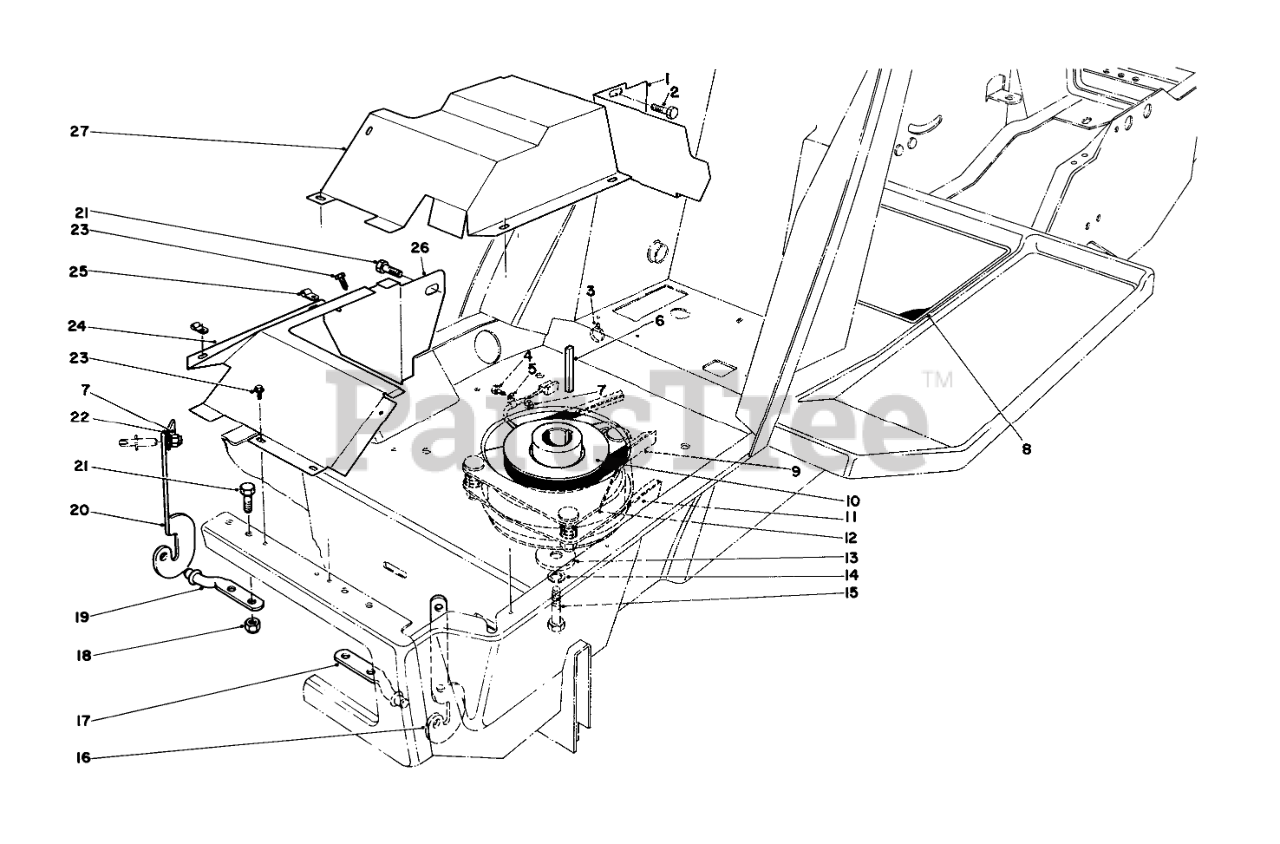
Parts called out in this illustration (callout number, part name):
1	EXH SHIELD SUPT B
2	SCREW-HH
3	TIE-MOUNT, PUSH
4	SCREW-HH
5	CLAMP
6	KEY-SQUARE
7	NUT-LOCK, NI
8	OPERATION DECAL
9	V BELT
10	Pulley
11	V BELT
12	Clutch Assembly-Deck
13	WASHER-CLUTCH
14	WASHER-LOCK
15	SCREW-HH
16	L.H. HINGE BRACKET
17	LH HOOD HINGE PIN
18	NUT-LOCK, CONE
19	RH HOOD HINGE PIN
20	RH HINGE BRKT
21	SCREW-HH
22	SCREEN SUPT BRKT
23	SCREW-HWHTF
24	Heat Shield
25	CABLE CLAMP
26	Support Heat Shield
27	HEAT SHIELD WA B
